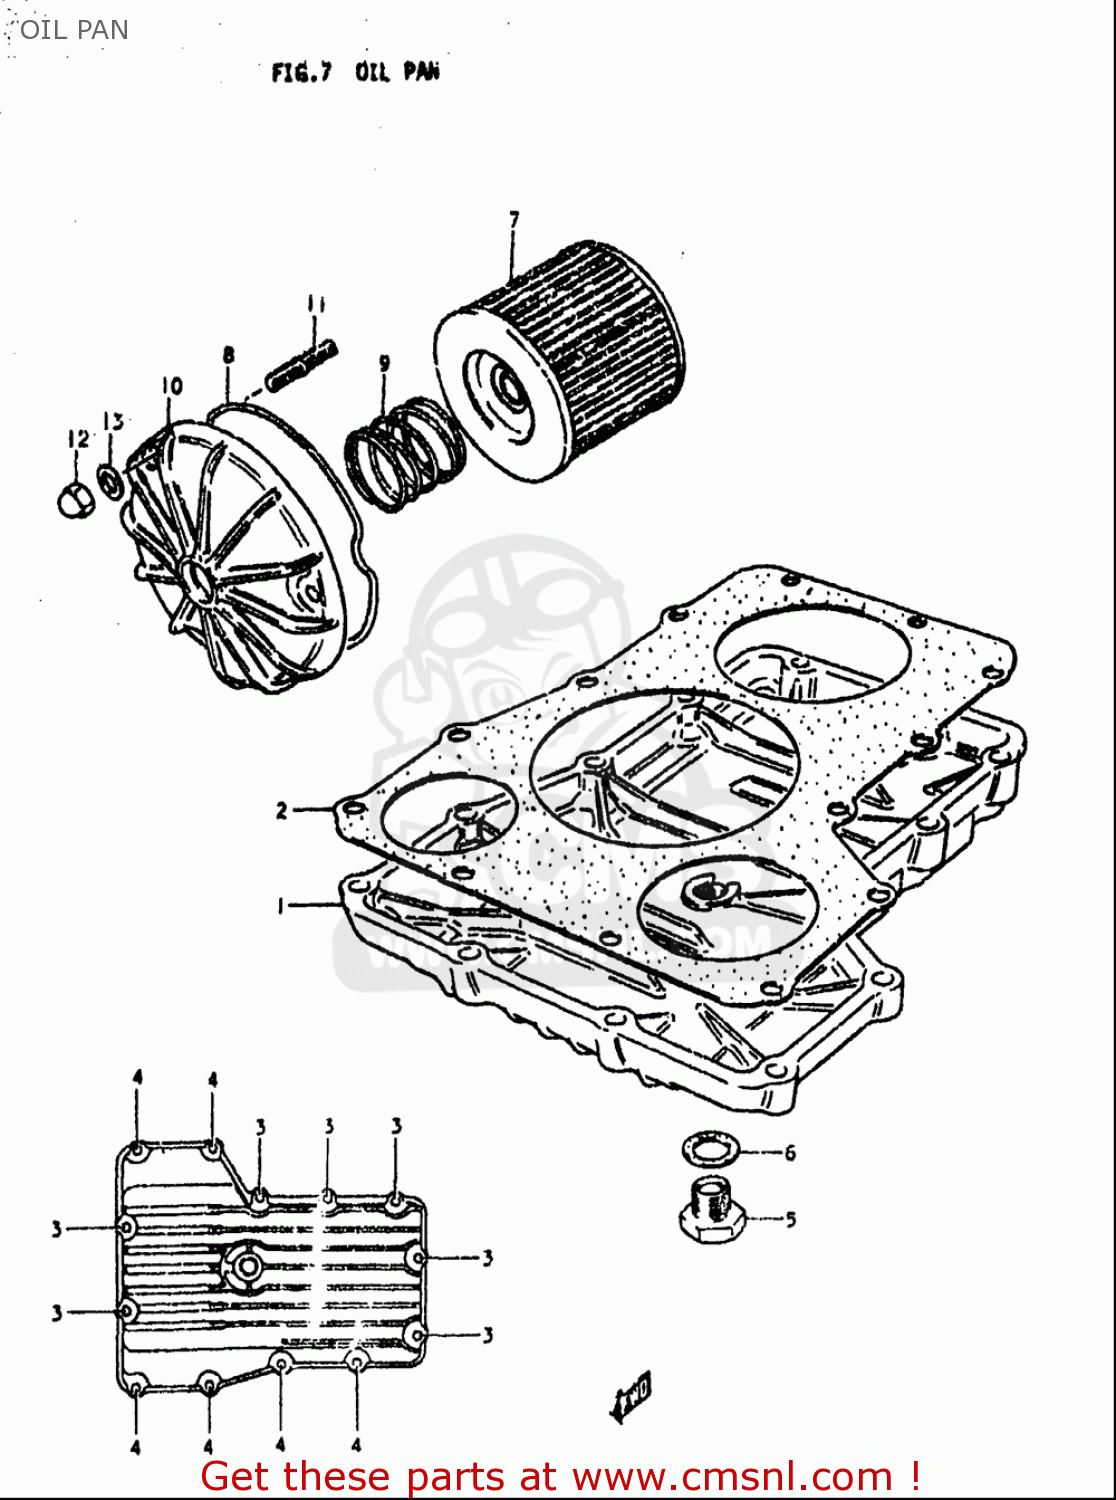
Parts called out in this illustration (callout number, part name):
1	PAN,OIL
2	GASKET,OIL PAN (NAS)
3	BOLT
4	BOLT
5	PLUG(MAGNETO)
6	GASKET(14X19.2X2) (NAS)
7	FILTER ASSY,ENGINE OIL
8	O RING,OIL FILTER CHAMBER CAP
9	SPRING
11	BOLT,STUD
12	NUT
13	WASHER
